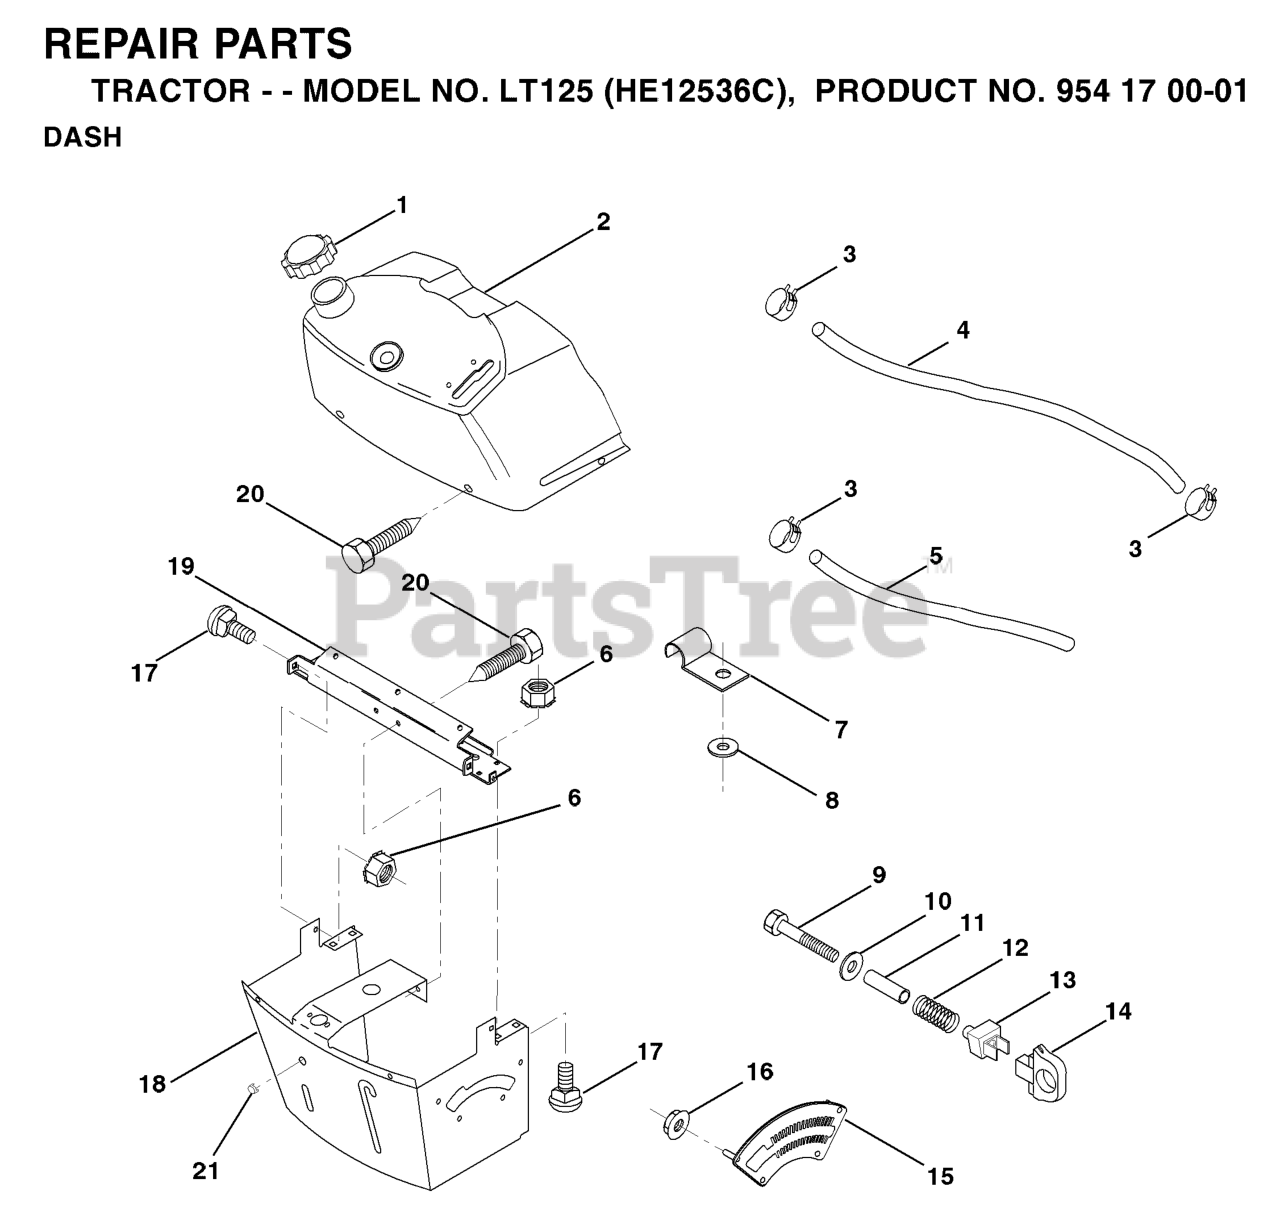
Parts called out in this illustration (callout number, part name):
1	CAP.FUEL.GREY
2	TANK ASM DASH LR
3	HOSE CLAMP
4	FUEL LINE
5	FUEL LINE T
6	Nut, Keps Blk Hex 1/4-20 UNC
7	CLIP T
9	BOLT HEX FIN 1/4-20X1 3/4
10	WASHER
11	SPACER SPLIT
12	SPRING.COMPRESSION
13	KNOB HGT RETAINER
15	ADJUSTER QUAD
16	NUT.PUSH.3/16
18	SUPT ASSY DASH
19	CROSS BRACE
